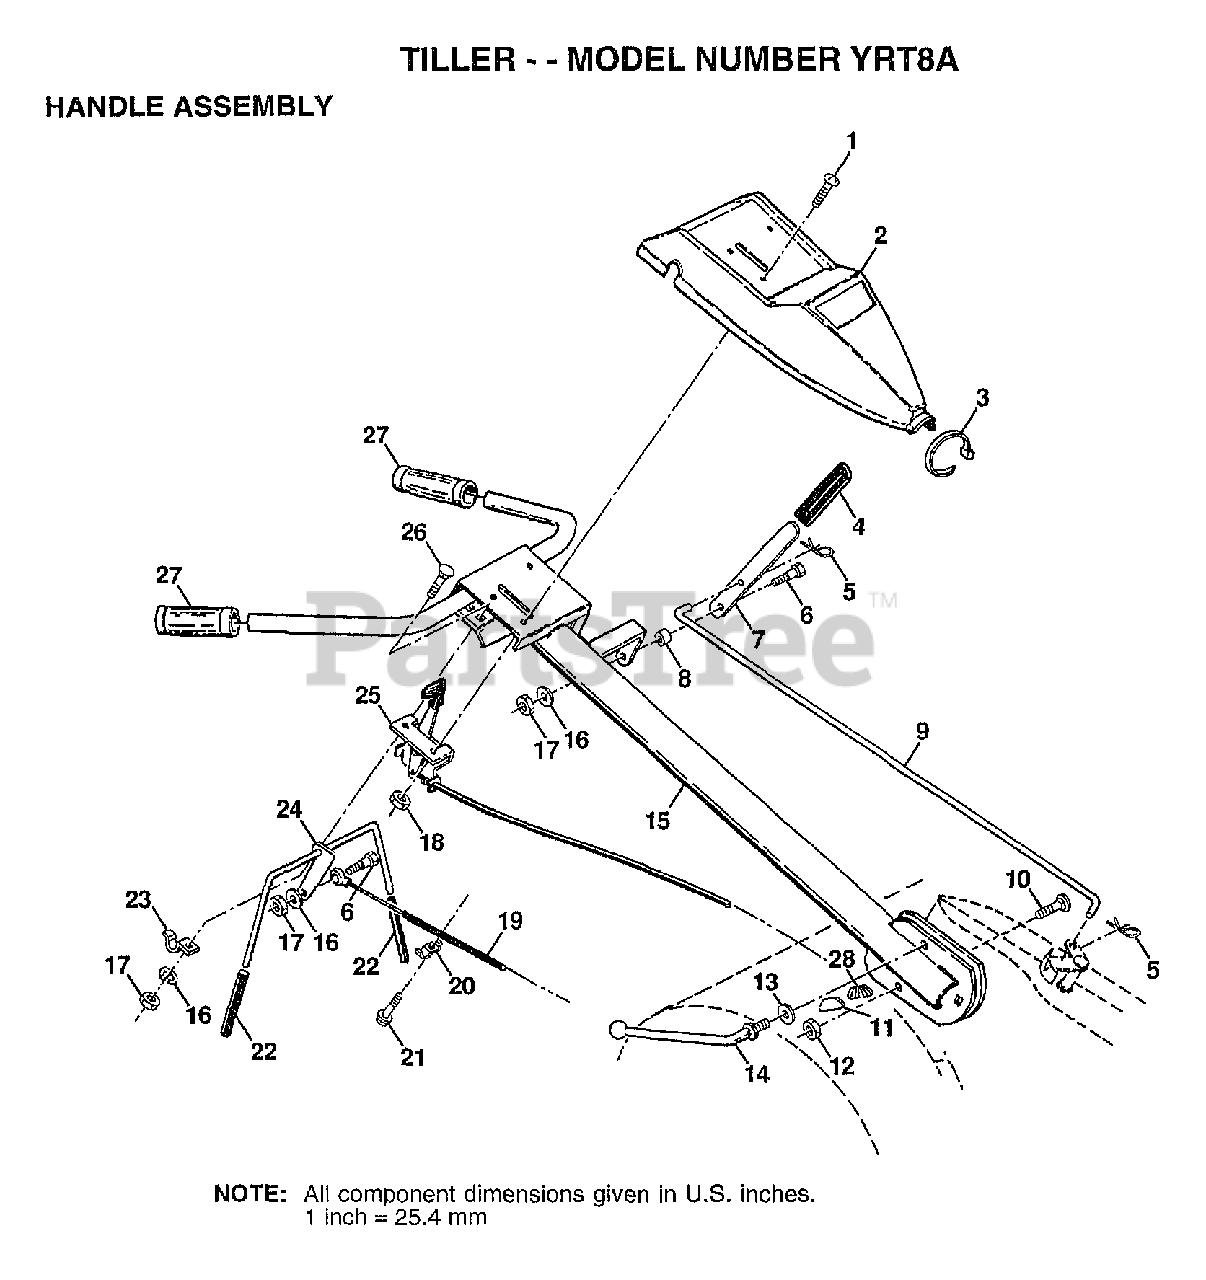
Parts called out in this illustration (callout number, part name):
1	SCREW.PNHD.10-24
2	"PANEL,CONT TI"
3	TIE CABLE CRT
4	GRIP T
5	RETAINER M
6	SHOULDER BOLT ST
7	SHIFT HANDLE CRT
8	GROMMET CRT
9	ROD.SHIFT
10	BOLT D
11	LOCK CRT
12	LOCKNUT
13	WASHER CRT
14	LEVER LOCK CRT
16	LOCKWASHER
19	CABLE-CLUTCH CRT
20	CONDIUT CLIP T
22	GRIP BAR CRT
24	"ASSY CONTROL, BAR"
25	CONTROL.THROTTLE
26	BOLT
27	GRIP NUB SNGL HDL
28	LOCK.HANDLE
